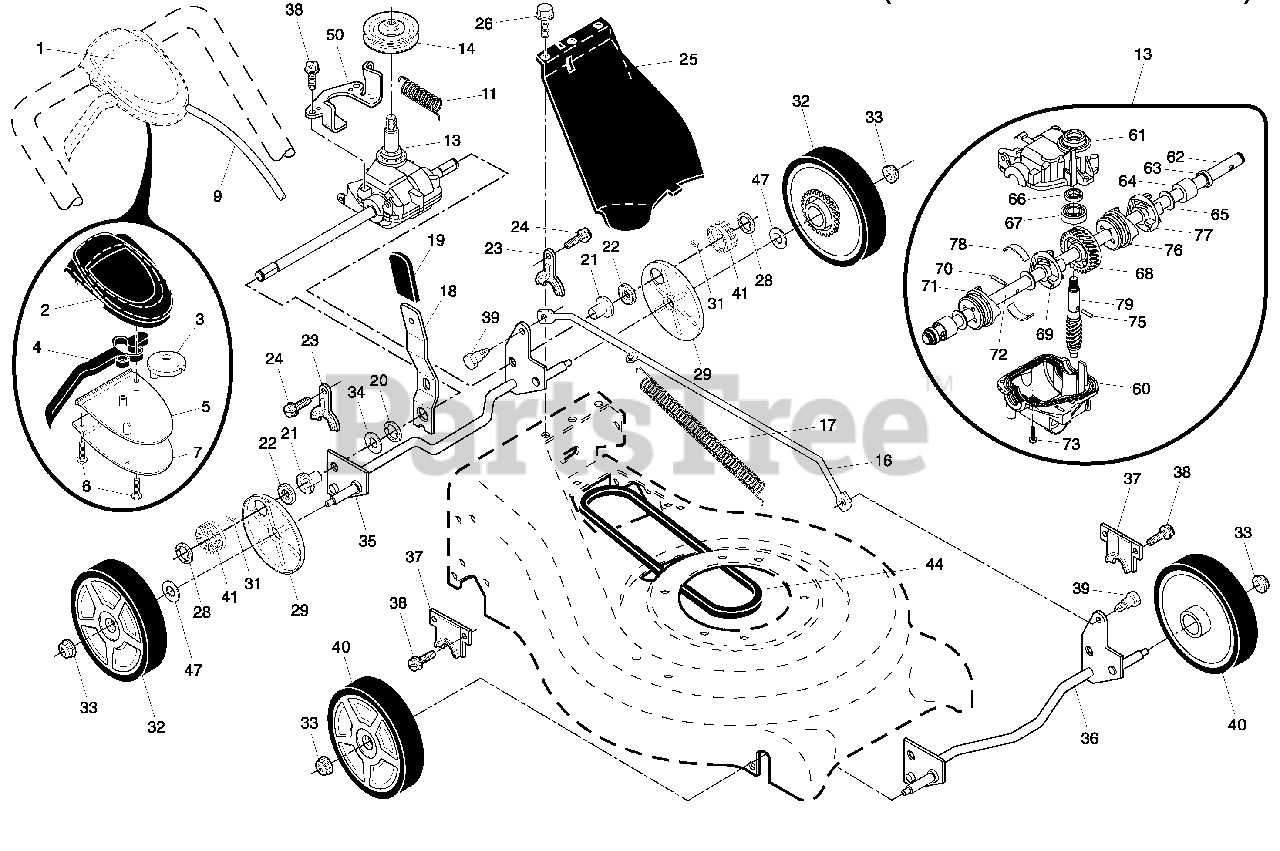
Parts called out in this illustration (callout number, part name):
1	Drive Control Assembly
2	Cover, Top
3	Pulley
4	Lever, Drive Control
5	Cover, Bottom
6	Screw
7	Mounting Bracket
9	Cable, Drive
11	Spring, Return
13	Gear Case Assembly
14	Pulley, Drive
16	Rod, Connecting
17	Spring, Extension
18	Spring, Selector
19	Knob, Selector Spring
20	E-Ring 7/8
21	Bearing
22	Bearing, Ball
23	Retainer, Drive Assembly
24	Screw, Tapping, Hex Head 1/4-20 x 3/4
25	Cover Drive
26	Screw, Threaded, Rolled #10-25 x 1/2
28	E-Ring 7/16
29	Cover, Dust, Wheel
31	Pawl, Drive
32	Wheel & Tire Assembly, Rear (Driven) 8 x 1-3/4
33	Nut, Flangelock 3/8-16
34	Washer
35	Shaft Assembly, Rear
36	Shaft Assembly, Front
37	Retainer, Front Shaft
38	Screw #12 x 5/8
39	Bolt, Shoulder, Semi-Gimlett Point
40	Wheel & Tire Assembly, Front 8 x 1-3/4
41	Pinion, Gear
44	V-Belt
47	Washer
50	Belt Keeper
60	Case, Lower
61	Case, Upper
62	Shaft, Output, Long
63	Seal, Output Shaft
64	Bushing
65	Washer
66	Seal, Worm Shaft
67	Bearing, Ball
68	Gear, 28 Teeth
69	Fixed Dog Clutch, LH
70	Pin, Output Shaft
71	Movable Dog Clutch, LH
72	Shaft, Output, Short
73	Screw, Case
75	Pin, Worm Shaft
76	Fixed Dog Clutch, RH
77	Movable Dog Clutch, RH
78	Spring, Leaf
79	Shaft, Worm
